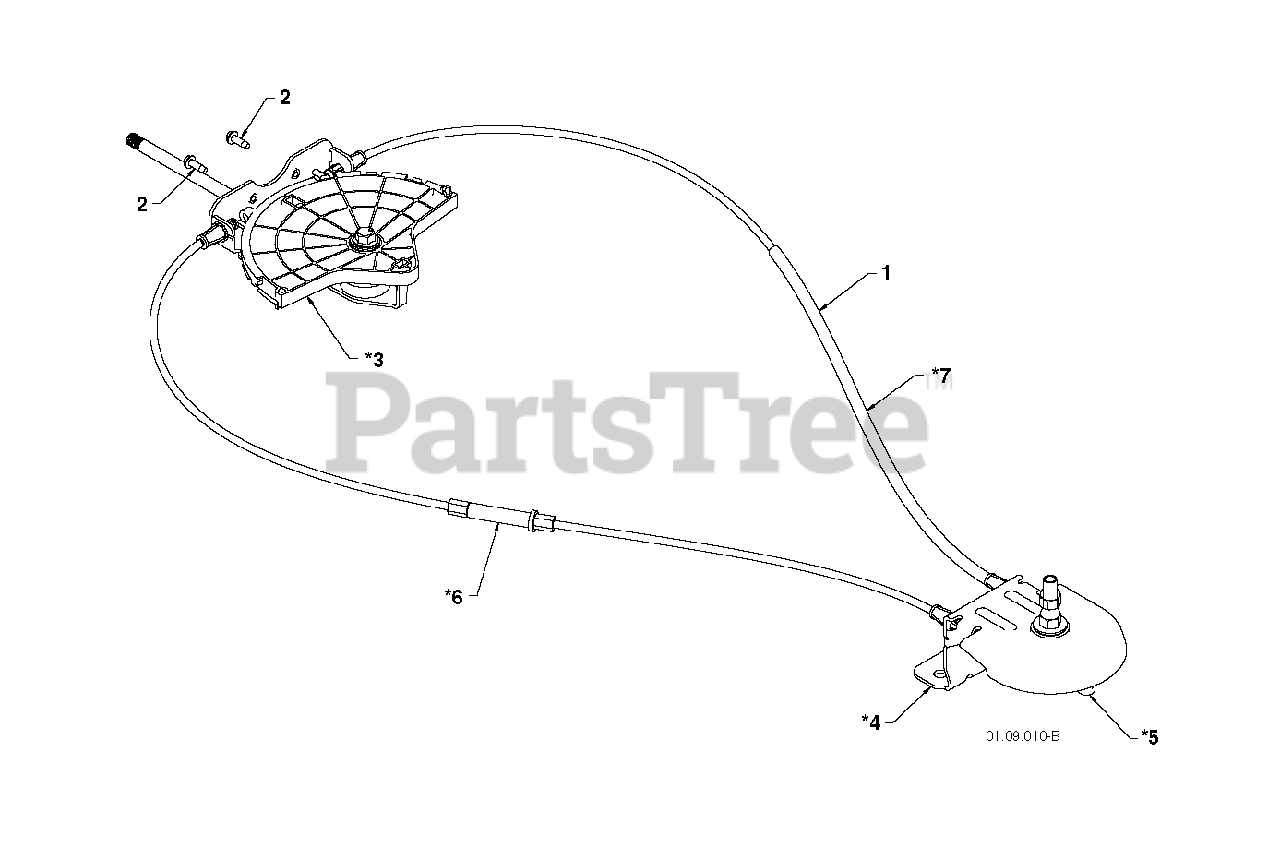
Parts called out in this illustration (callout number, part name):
1	LEVER/CABLE.ASM.ROTATOR
2	SCREW #10-24 X 5/8
3	CHUTE.ROT.HEAD.SERVICE
4	SNOW.PIVOT.BRKT.BLK.SERVICE
5	SNOW.PIVOT.PULLY
6	SNOW.CBL.ASM.ADJ.SERVICE(74)
7	SNOW.CBL.ASM.SERVICE(428272)
